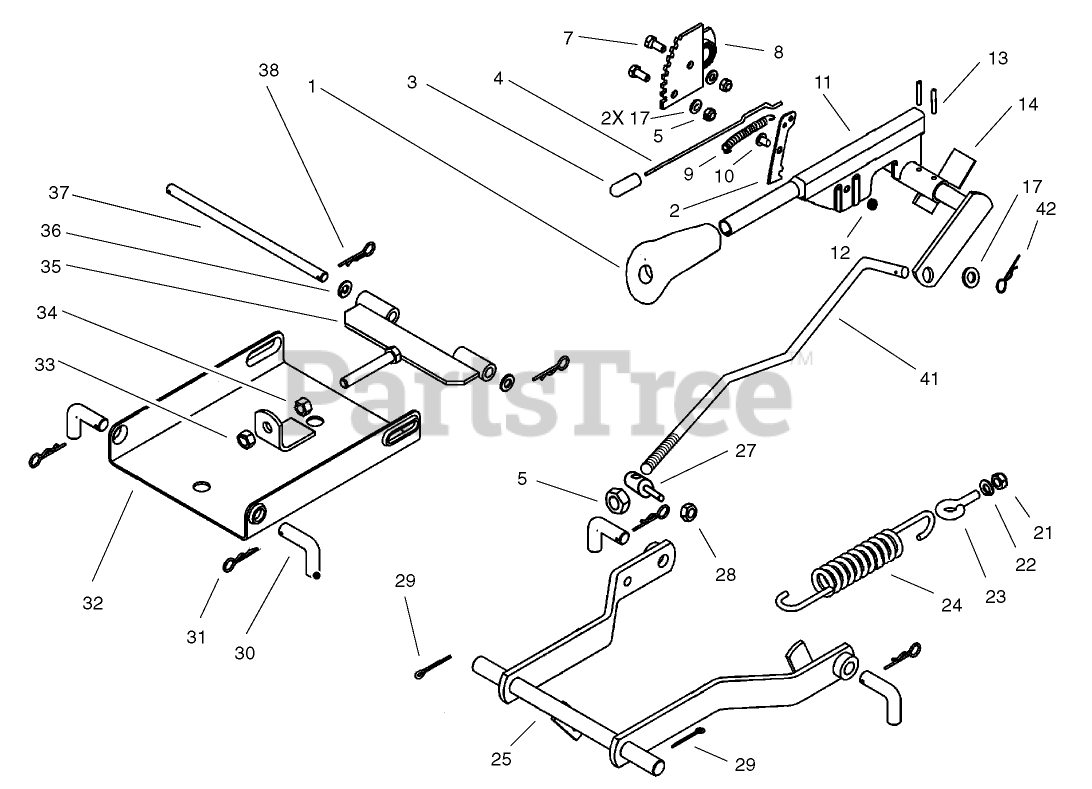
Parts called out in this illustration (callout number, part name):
1	GRIP-HANDLE
2	RATCHET-PLATE, PIVOT
3	BUTTON-PLUNGER
4	ROD-CONNECTION
5	NUT-LOCK, NI
7	SCREW-HH
8	SEGMENT-GEAR
9	SPRING
10	PIN-LEVER, ARM
11	LEVER-ARM, HEIGHT ADJ.
12	CLIP-PIN
13	PIN-SPRING
14	SHAFT-HEIGHT ADJ.
17	WASHER-PLAIN
21	NUT-LOCK, NI
22	WASHER-FLAT
23	BOLT-EYE
24	SPRING-LIFT
25	PIVOT ARM ASM
27	PIN-LIFTING
28	NUT-LOCK, NI
29	PIN-COTTER
30	PIN-BENT
31	PIN-HAIR
32	SUSPENSION-MOWER DECK, FRONT
33	NUT-HEX
34	NUT-HEX
35	HOLDER-FRONT
36	WASHER-FLAT
38	PIN-HAIR
41	ROD-HEIGHT, ADJ.
42	PIN-COTTER
